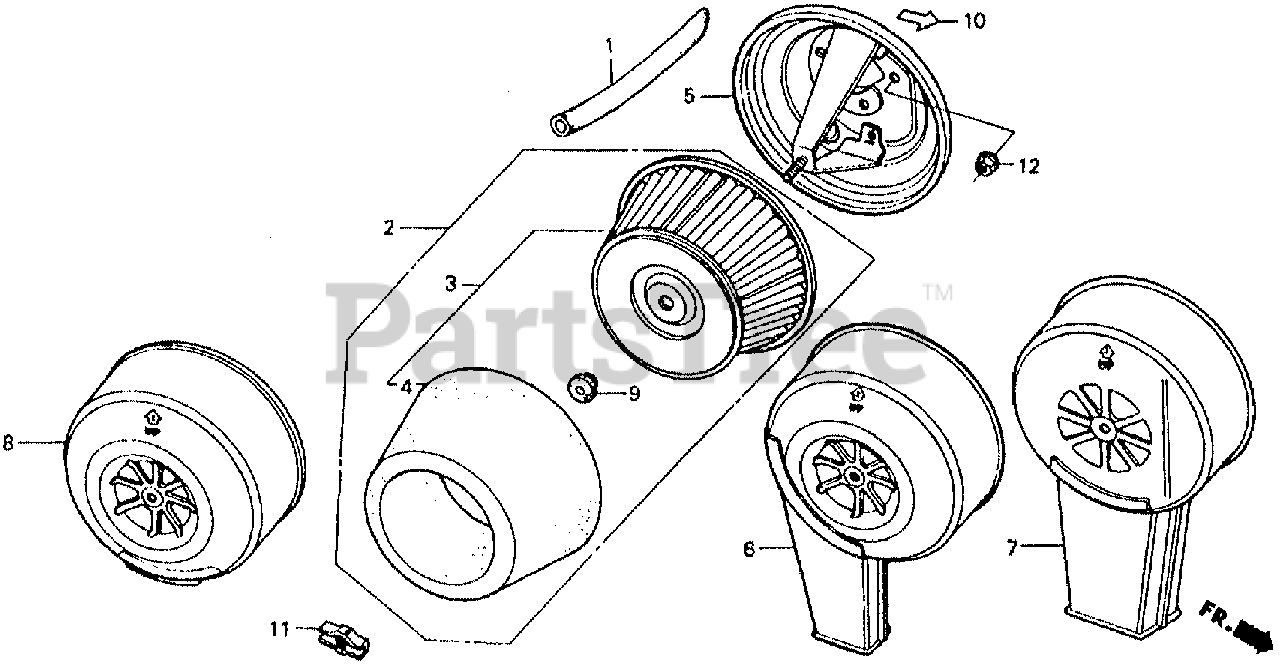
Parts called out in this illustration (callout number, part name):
1	TUBE, BREATHER
2	ELEMENT SET, AIR CLEANER
2	ELEMENT, AIR CLEANER
3	ELEMENT SET, AIR CLEANER
3	ELEMENT, AIR CLEANER
4	FILTER (OUTER)
5	HOUSING, AIR CLEANER
7	COVER, AIR CLEANER
8	COVER, AIR CLEANER
9	GROMMET, AIR CLEANER
10	MARK, CHOKE
11	WINGNUT, AIR CLEANER COVER
12	NUT, FLANGE (6MM)
